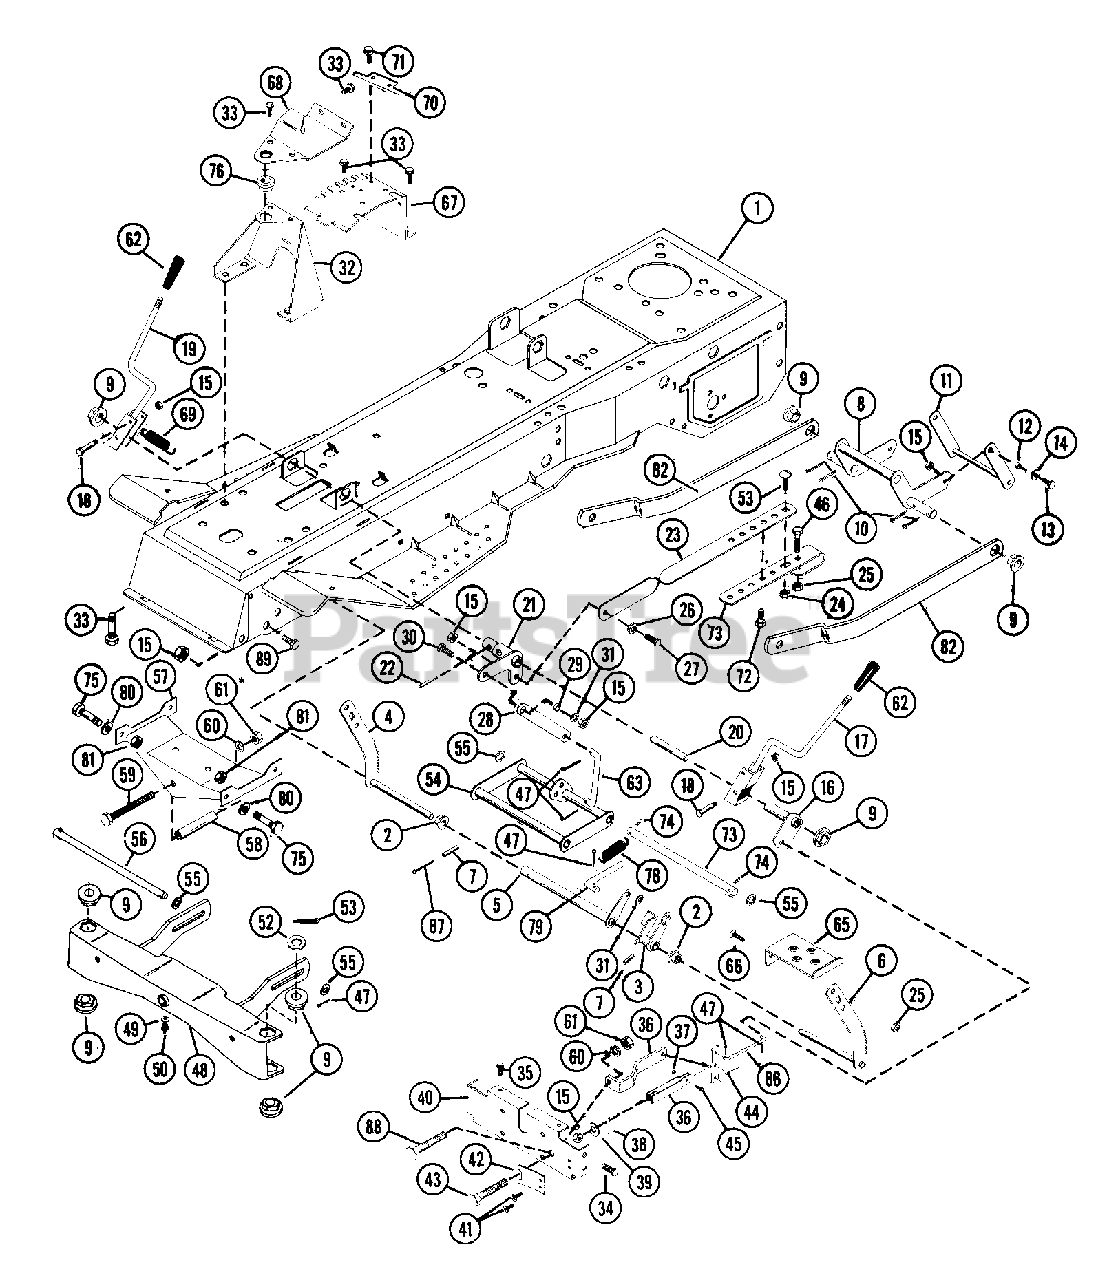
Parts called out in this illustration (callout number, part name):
1	FRAME
2	FLANGE BUSHING
3	CLUTCH ARM
4	CLUTCH PEDAL ARM
5	BRAKE ARM
6	BRAKE PEDAL ARM
7	PIN-ROLL .188X1.00
8	REAR MOWER HANGER
9	FLANGE BUSHING
10	PIN-COTR .09X1.0 PL
11	REAR MOWER LINK
12	SPACER BUSHING .5 X .32 X .21
13	BLT-HEX .31-18X.75 PL GR5
14	WSHR-FL-STL .344X1.125X.063PL
15	NUT-LK .312-18 GR A PL
16	CLUTCH ARM
17	MOWER CLUTCH LEVER
18	SHOULDER BOLT .436 X .912
19	MOWER HEIGHT LEVER
21	MOWER LIFT ARM
22	PIN-ROLL .188X1.25
23	LIFT STRAP
24	NUT-LK-CTR .375-16 GR A PL
25	NUT-LK-JAM-CTR .375-16 PL
26	SPACER -SHLD .344X.500X.469
27	BLT-HEX .31-18X1.25 PL GR2
29	SPACER
30	BLT-HEX .31-18X.75 PL GR2
31	WSHR-FL-STL .323X.625X.062 PL
32	STEERING SUPPORT
33	BLT-SERHFWH .31-18X.50 PL
34	BLT-HEX .31-18X.63 PL GR 2
35	SCR-TAP .250-20X.50 HXSLHDPL
36	ADJUSTMENT YOKE
36	FRONT ANCHOR
37	CLUTCH LINK
38	PIN-ROLL .188X1.00
39	WSHR-FL-STL .505X1.000X.062
40	MOWER ADJUSTMENT BRACKET
41	SCR-TAP 10-24X.25 CRSLPH PL 1A
42	LOCK SPRING
43	CAP SCREW
44	SPACER BUSHING .5 X .32 X .21
45	BLT-HEX .31-18X.88 PL GR2
46	BLT-HEX .38-16X1.50 PL GR2
47	PIN-COTR .09X.75 PL
48	AXLE
49	WSHR-FL-STL .265X.500X.087 PL
50	SPIN DRIVE ZERK FITTING
52	WSHR-FL-STL .755X1.375X.062 PL
53	BLT-RDHDSQNK .38-16X.75 SHT PL
54	FRONT LIFT ARM
55	WSHR-FL-STL .505X.880X.072 PL
56	HANGER PIN
57	AXLE BRACKET
58	TUBE AXLE PIVOT
59	BLT-HEX .50-13X4.00 PL GR2
60	WSHR-LK .500X.151 HVY PL
61	NUT .50-13 PL
62	HANDLE
63	LINK
66	BLT-RDHDSQNK .38-16X.62 GR5 PL
67	QUADRANT
69	SG-TENS .092X.69X1.75 WLD 54
71	BLT-SERHFWH .25-20X.50 PL
72	BLT-HEX .38-16X.75 PL GR2
73	ADJUSTMENT STRAP
74	PIN-HAIR INT .08X.38X1.42 YWZC
75	BLT-SERRDHD SL .31-18X.75 YZ
76	FLANGE BUSHING
77	NUT .50-13 PL
78	SG-TENS .035X.45X2.75 WLD 3.5
79	BRAKE ROD
80	WSHR-LK .375X.094 MED PL
81	NUT-FLG. .312-18 PL
82	POSITIONING ARM
83	WSHR-LK .500X.151 HVY PL
85	BLT-HEX .50-13X1.25 PL GR2
87	PIN-COTR .09X1.87 PL
88	BLT-HEX .50-13X1.25 PL GR2
89	BLT-HEX .31-18X.50 PL GR2
